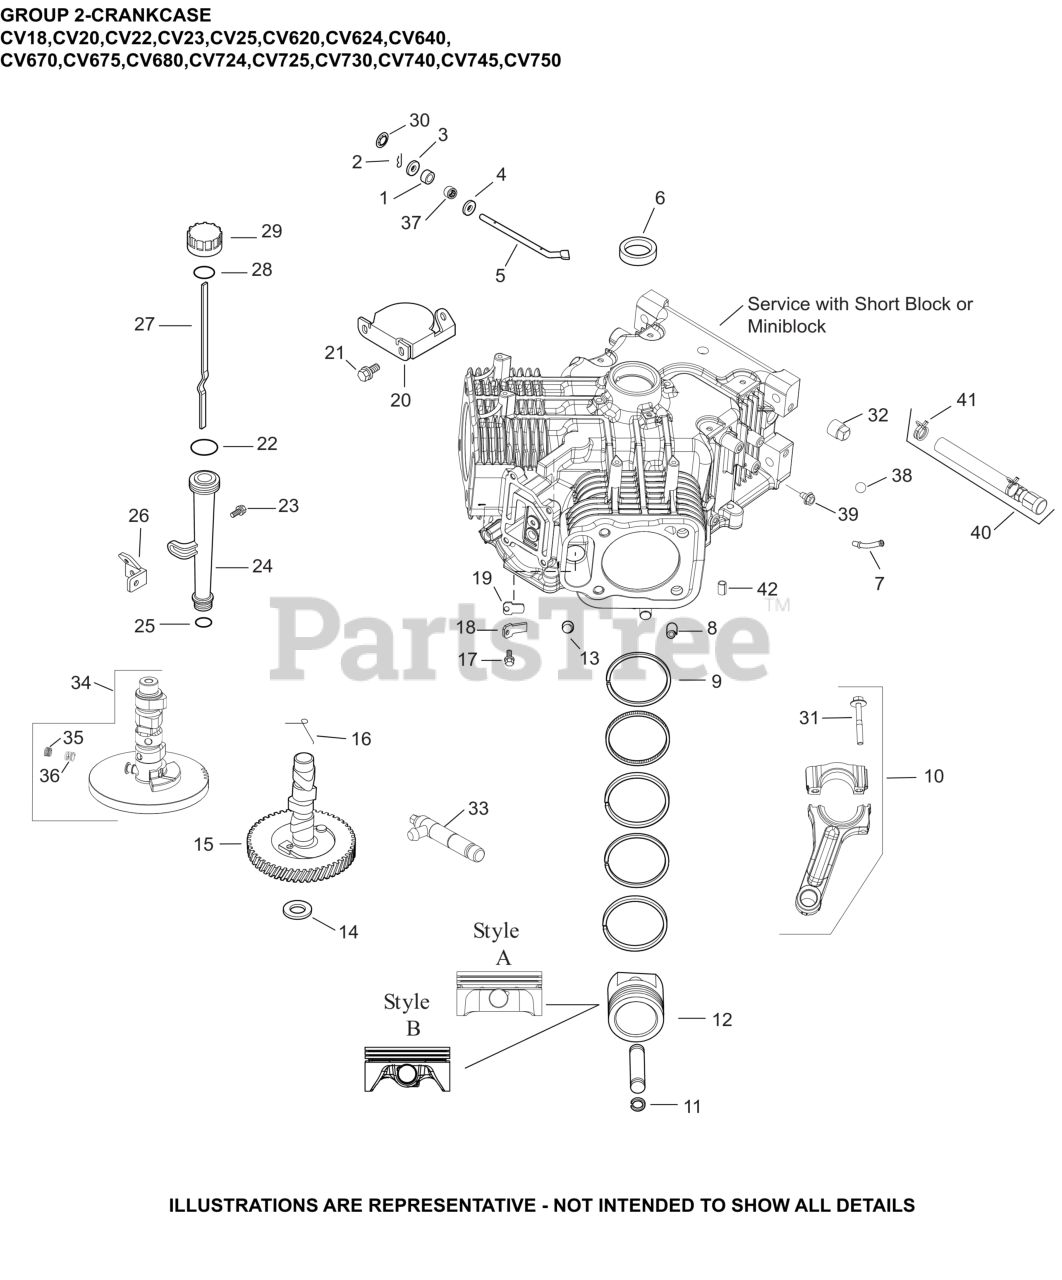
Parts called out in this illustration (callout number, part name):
1	SEAL, GOVERNOR CROSS SHAFT
3	WASHER, FLAT 9 MM
4	WASHER, FLAT 11/32"
5	SHAFT, GOVERNOR CROSS-(#2414439S)
6	SEAL, OIL (HELIX LIP)
8	PIN, LOCATING
9	RING SET(STD)STYLE B-1.2mm Tp RING THICK
9	RING SET(.08)STYLE B-1.2mm RING THICK
9	RING SET(.25)STYLE B-1.2mm Tp RING THICK
9	RING SET(.50)STYLE B-1.2mm Tp RING THICK
10	ROD, ASSEMBLY CONNECTING
11	RETAINER, PISTON PIN
12	KIT, PISTON 725CC (STD) STYLE B
12	KIT, PISTON 725CC (.08) STYLE B
12	KIT, PISTON 725CC (.25) STYLE B
12	KIT, PISTON 725CC (.50) STYLE B
13	PLUG, CUP
15	KIT, CAMSHAFT-(#2401226S)
17	SCREW, FLG THD FRM M5X.8X10
18	RETAINER, BREATHER REED
19	REED, BREATHER-(#2440207S)
22	O-RING, UPPER OIL FILL TUBE
23	SCREW, FLG THD FRM M5X0.8X13
24	TUBE ASSEMBLY
25	O-RING, LOWER OIL FILL TUBE
26	BRACKET, OIL FILL TUBE
27	DIPSTICK, ASSY
28	O-RING, DIPSTICK
29	KIT, OIL FILL CAP (YELLOW)
30	RETAINER, RING
31	KIT, ROD BOLTS-(#25086677S)
39	SCREW, THREAD FORMING
